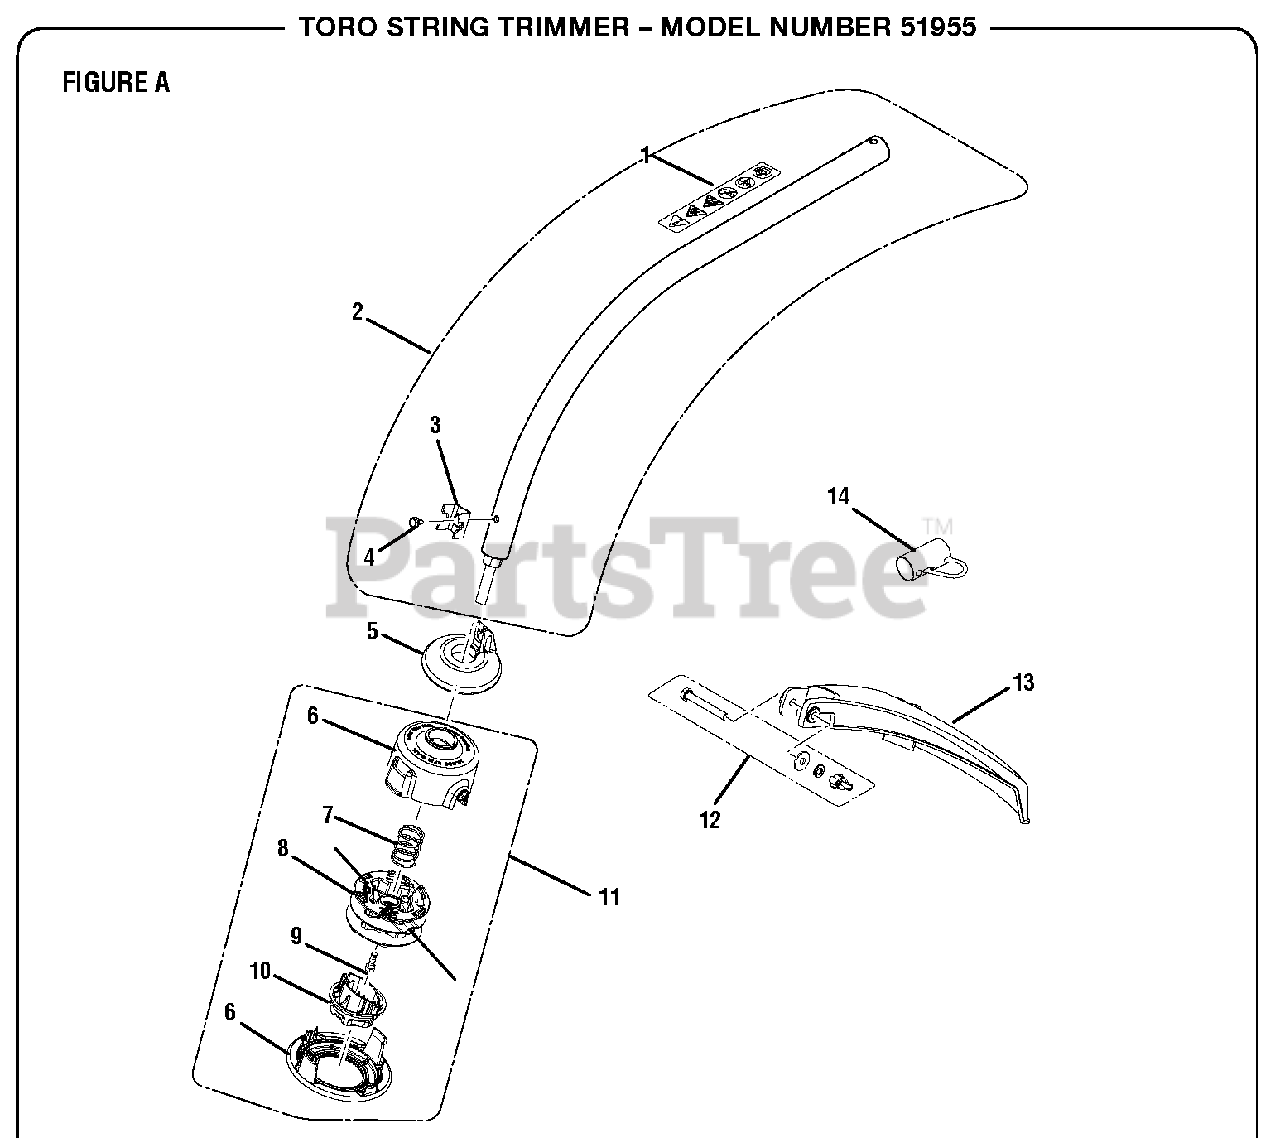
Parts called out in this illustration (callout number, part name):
1	Warning Label
2	Curved Shaft Assembly
4	Screw (#10-32 x 3/8 in., Hex Washer Hd.)
5	Grass Shield
6	Stringhead Housing
7	Compression Spring
8	Spool
9	Bolt (5/16-18 x 1/2 in.)
10	Bump Knob
11	Trimmer Head Assembly (.095)
12	Fastener Parts Kit
13	Guard
14	Hanger Cap
